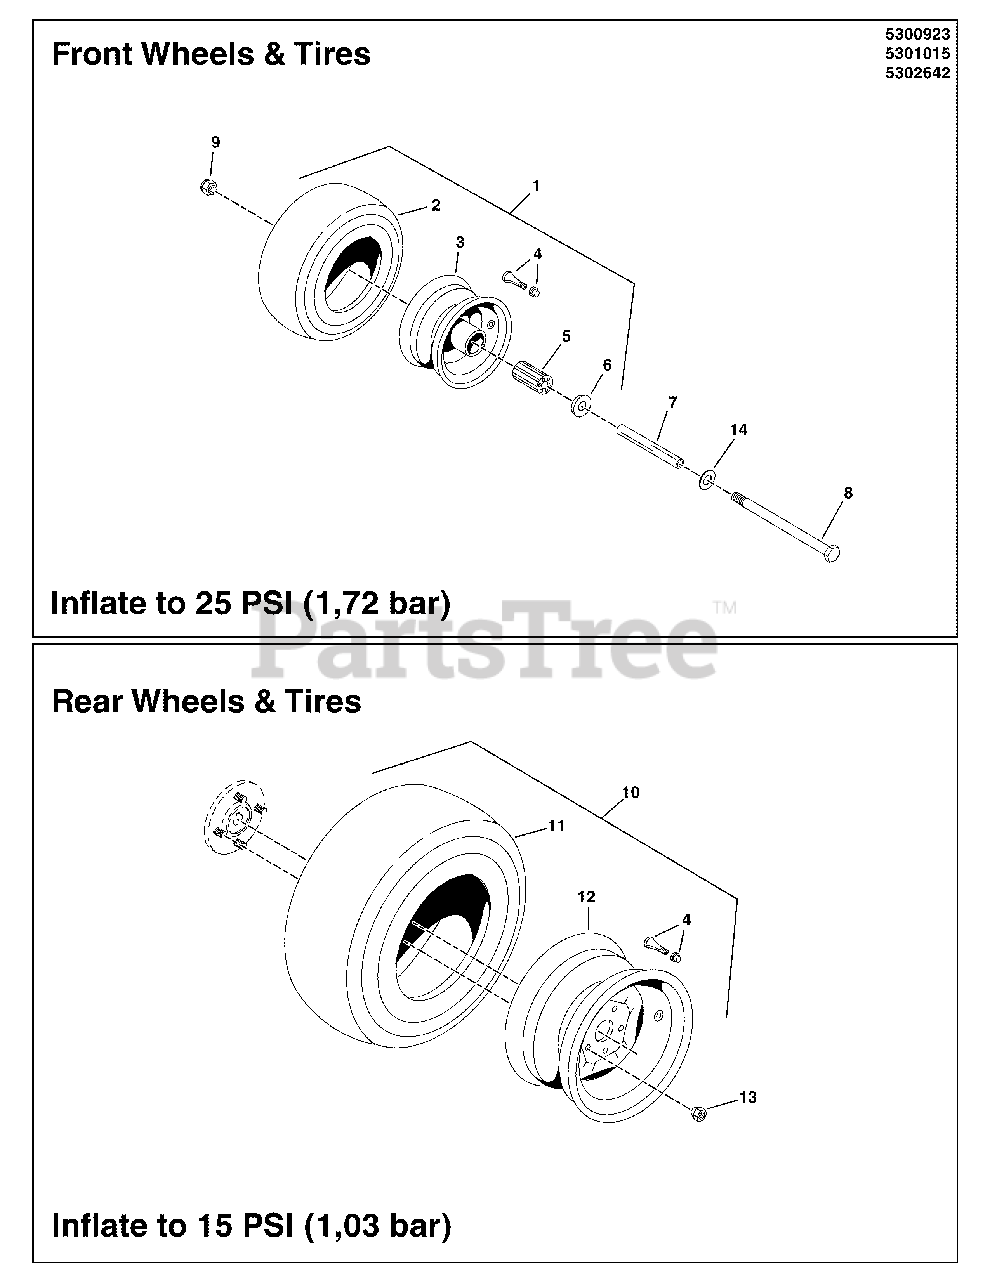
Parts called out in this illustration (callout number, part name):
1	WHEEL, CASTER, 11 X 4.0-5 SILVER BEAD LO
2	TIRE, FRONT, 11 X 4.0 - 5 (SV)
3	WHEEL ASSEMBLY, 11 X 4.0 - 5 TIRE CMP (SV)
4	VALVE STEM & CAP-AIR .453DIA 0.88LG (SV)
5	BEARING, CASTER WHEEL, 11 X 4.0 - 5 BEAD LOCK (SV)
6	RETAINER, BEARING (TWO PER TIRE)(SV)
7	AXLE, Front Caster
8	BOLT, HEX, 1/2-13 X 7, GD 8, YZ
9	NUT, 1/2-13 HEX NYLOCK FLANGE
10	TIRE ASSM, 20 X 7 - 10, TURF, 4 BOLT
10	TIRE ASM, REAR, 20 X 10.0 X 10
11	TIRE, 20 X 7 -10 NHS, TURF MASTER
11	TIRE, REAR, 20 X 10.0 X 10
12	WHEEL, 10 X 6.00 4/4 SOLID, F237
12	WHEEL, 10X7.00 4/4 SOLID F237 2.625 OS (SV)
13	NUT, 1/2-20, FOR WHEEL BOLT SILVER
14	WASHER, 1/2 SAE
